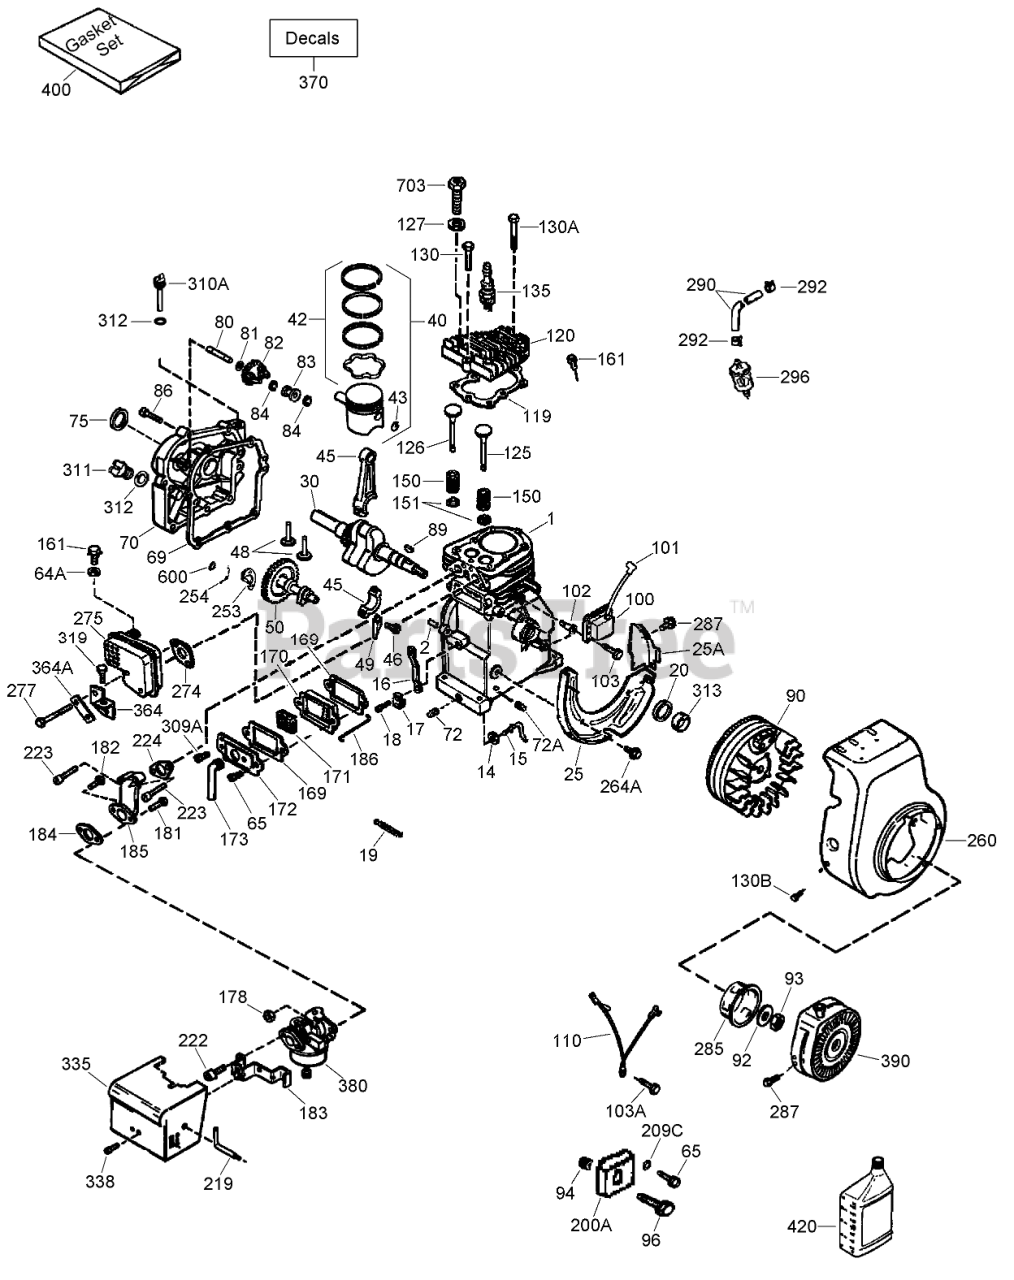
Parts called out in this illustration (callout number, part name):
1	Cylinder Asm (Includes 2, 20, 72, 125)
2	Pin-Dowel
14	Washer-Flat
15	Rod-Governor
16	Chute Idler Arm ASM
17	Clamp-Lever, Governor
18	Screw (T-15, 8-32 x 19/64)
19	Spring-Extension
20	Seal-Oil
25	Baffle-Housing, Blower
25A	Extension-Baffle
30	Crankshaft
40	Piston, Pin and Ring Set (.010 O S) (Includes 41-43)
40	Piston, Pin and Ring Set (Std) (Includes 41-43)
42	Ring Set (.010 O S)
42	Ring Set (STD)
43	Ring-Retaining, Piston Pin
45	Connecting Rod Asm (Includes 46, 49)
46	Bolt-Rod, Connecting
48	Lifter-Valve
49	Dipper-Oil
50	Camshaft (M C R)
64A	Washer
65	Screw (10-24 x 9/16)
69	Gasket-Cover, Cylinder
70	Cover-Cylinder (Includes 75-83, 311)
72	Plug-Drain, Oil (SQH 1/4-18)
72A	Plug-Pipe (Internal Hex, 1/4-18)
75	Seal-Oil
80	Shaft-Governor
81	Washer-Flat
82	Governor Gear ASM
83	Spool-Governor
84	Ring-Retaining
86	Screw (1/4-20 x 1-1/4)
89	Key-Flywheel
90	Flywheel
92	Washer-Belleville
93	Nut-Flywheel
94	Nut (10-32)
96	Bolt-Adjusting, R.P.M.
100	Ignition-State, Solid
101	Cover-Spark Plug
102	Stud-Mounting, Solid State
103	Screw (T-15, 10-24 x 15/16)
103A	Screw (10-32 x 1/2)
110	Wire-Ground
119	Gasket-Head, Cylinder
120	Head-Cylinder (Includes 130A)
125	Valve-Exhaust (1/32 O S) (Includes 151)
125	Valve-Exhaust (STD) (Includes 151)
126	Valve-Intake (1/32 O S) (Includes 151)
126	Valve-Intake (STD) (Includes 151)
127	Washer-Flat
130	Screw (5/16-18x1-1/2)
130A	Screw (5/16-18 X 2)
130B	Screw (1/4-20 x 1/2)
135	Spark Plug-Resistor (R J19 L M)
